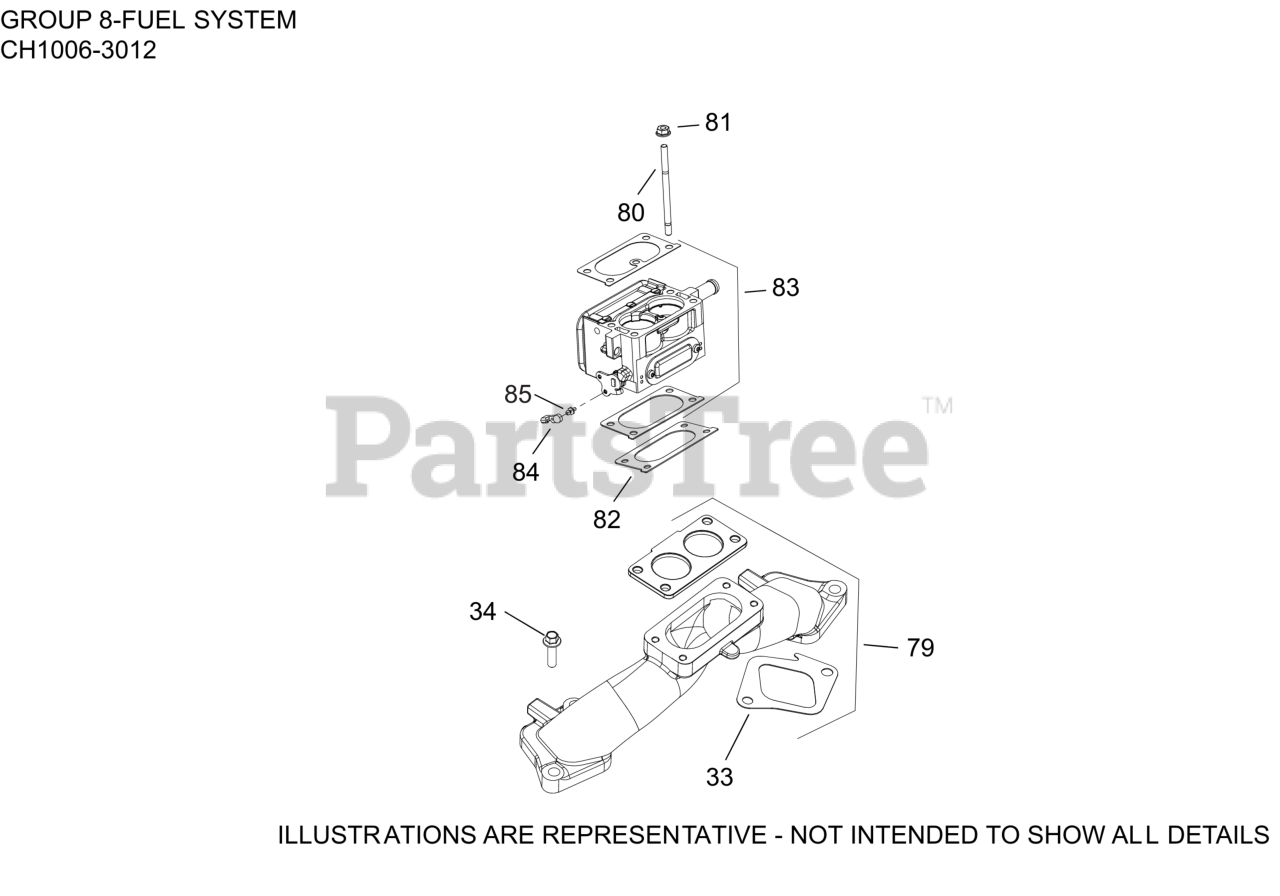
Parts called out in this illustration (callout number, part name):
33	GASKET, INTAKE MANIFOLD
34	SCREW, FLG M8X1.25X30
79	KIT, INTAKE MANIFOLD
81	NUT, HEX FLANGE
82	GASKET, MIXER
83	KIT, CARBURETOR
84	CUP, BALL JOINT
85	SCREW, CUP JOINT GOVERNOR
